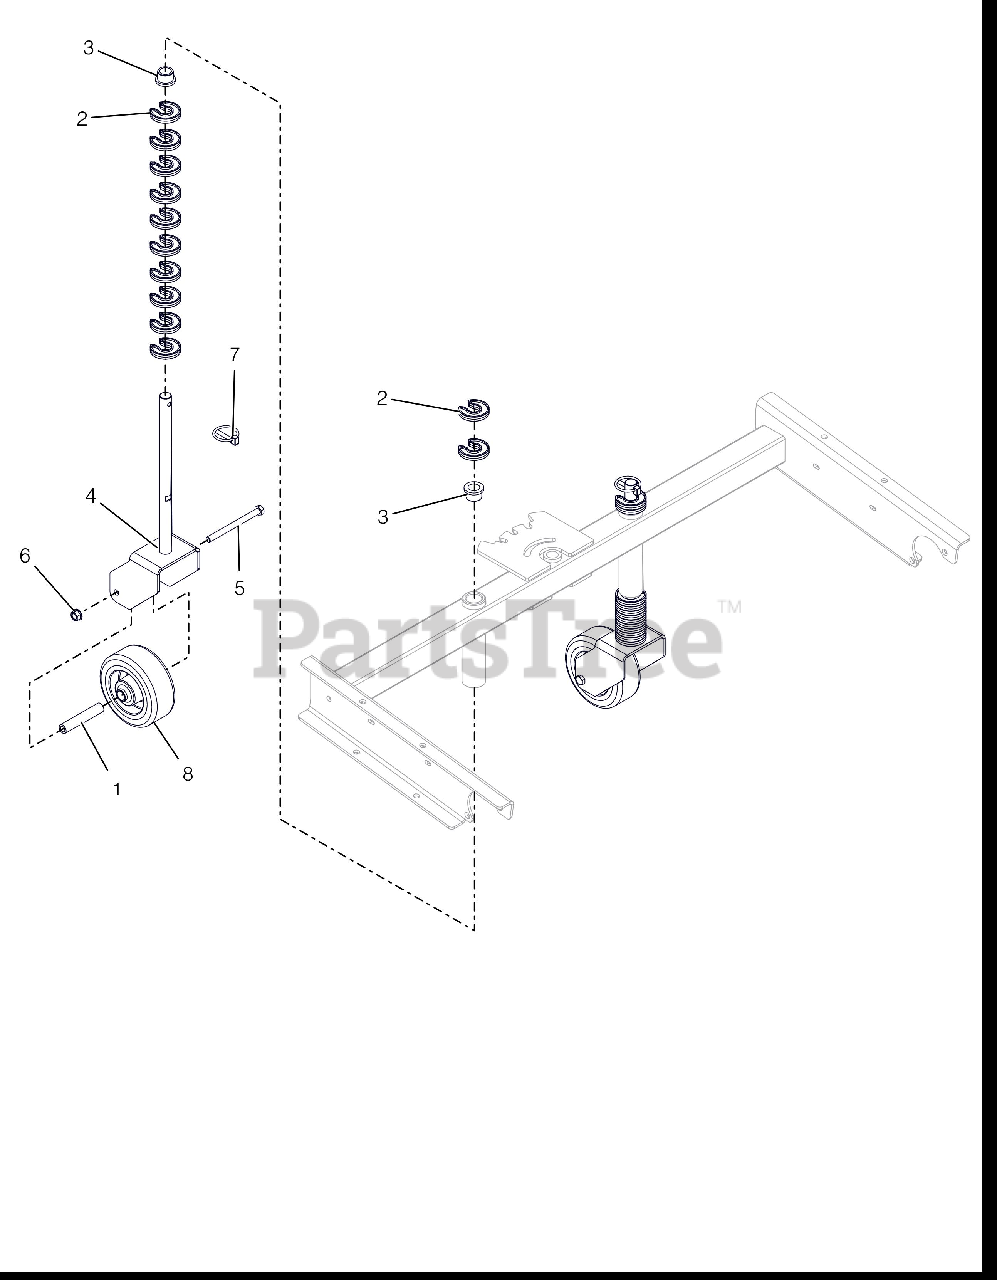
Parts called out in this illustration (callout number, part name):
1	SPACER, CASTER WHEEL
2	CLIP-HOC FIXED
3	BUSHING, FLANGE .75X.75X1.0
4	FORK, CASTER
5	@BLT-HEX .38-16X4.50 GR5 YWZC
6	@NUT-LK-TOP-FLG .38-16 YWZC
7	PIN, 1/4X1-9/16 LYNCH
8	WHEEL, CASTER - 5"OD
